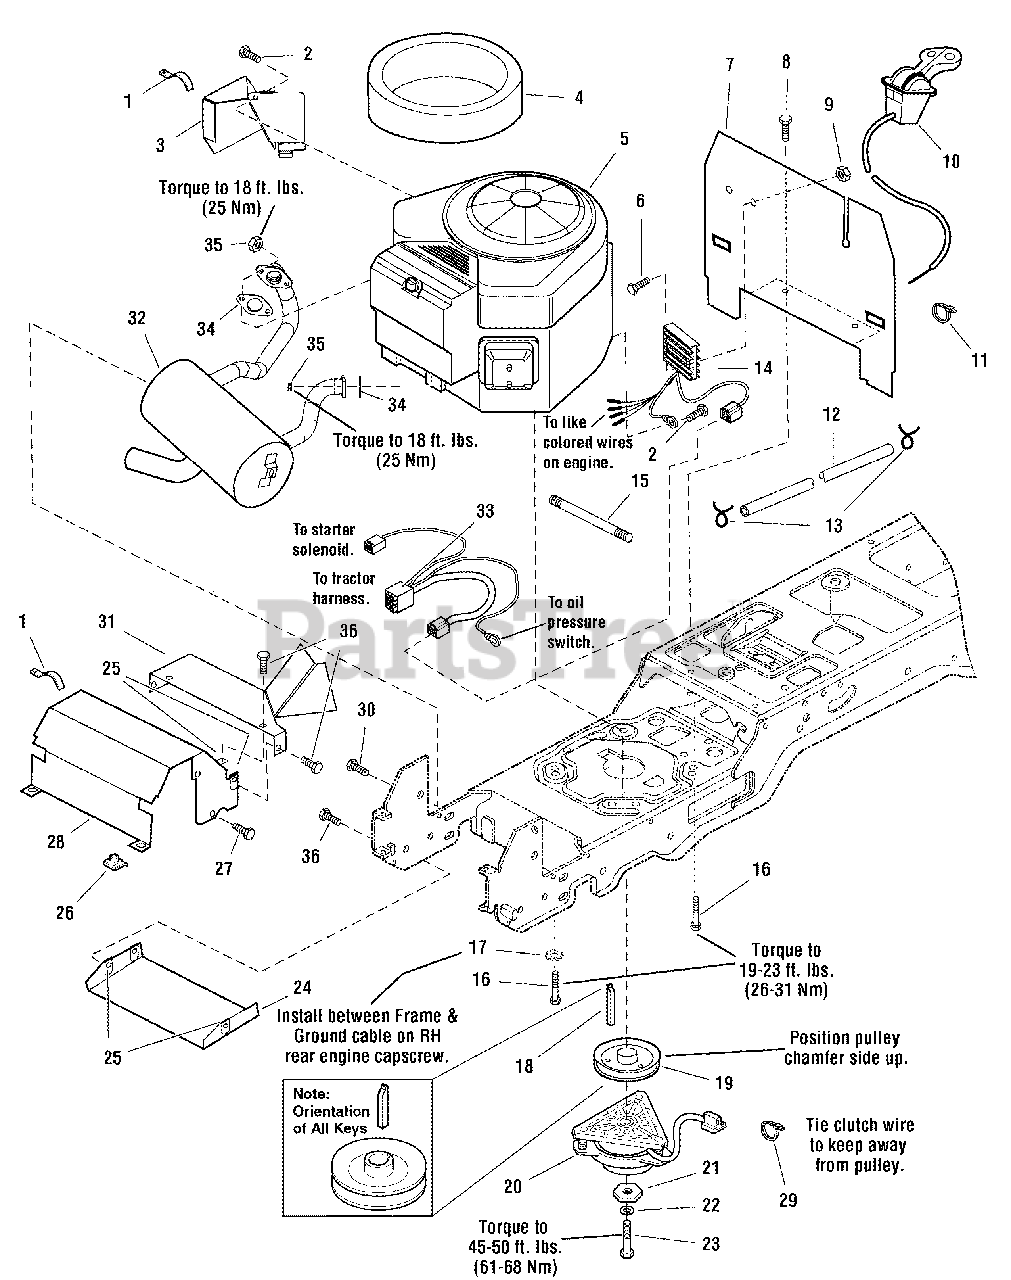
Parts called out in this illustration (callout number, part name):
1	CLIP, Wire 1/8
2	CAPSCREW, Hex Head, M06-1 x 12MM
3	SHIELD, Manifold, RH
6	CAPSCREW, Hex Head, Whiz Flangelock, 1/4-20 x 1, Black
8	CAPSCREW, Hex Washer Head Taptite, 1/2-20 x 1/2, Black
9	NUT, Hex Flange Lock, 1/4-20
10	CONTROL, Throttle Double 39" Long w/Knobs
11	TIE, Wire, 7-5/16" Long
12	HOSE, Fuel, 59" Long
13	CLAMP, Hose Type E
14	VOLTAGE REGULATOR
15	HOSE, Oil Drain, 6-1/2" Long, 3/8-18 Fittings
16	CAPSCREW, Hex Washer Head Taptite, 3/8-16 x 1-1/2
17	LOCKWASHER, External Tooth, 3/8
18	KEY, HI PRO, 1/4 x 2-1/2
19	PULLEY & HUB ASSEMBLY
20	CLUTCH, Electric, Ogura
21	WASHER, Hex, 7/16, Black
22	LOCKWASHER, 7/16
23	CAPSCREW, Hex Head, 7/16-20 x 3-3/4
24	SHIELD, Muffler Bottom
25	NUT, Speed, 1/4-20, Lug
26	NUT, Speed, 5/16-18, Lug, Black
27	CAPSCREW, Hex Washer Head Taptite, 1/4-20 x 3/8
28	DUCT, Muffler Top
29	TIE, Self Locking, 3-5/8" Long
30	CAPSCREW, Hex Washer Head Taptite, 5/16-18 x 1/2 Black
31	DUCT, Muffler
32	MUFFLER, Honda
33	WIRE ASSEMBLY, Jumper, Early Models for engine without 6 pin connector.
34	GASKET
35	NUT, Hex Flange, M06-1.0
36	CAPSCREW, Hex Head, 1/4-20 x 3/8
